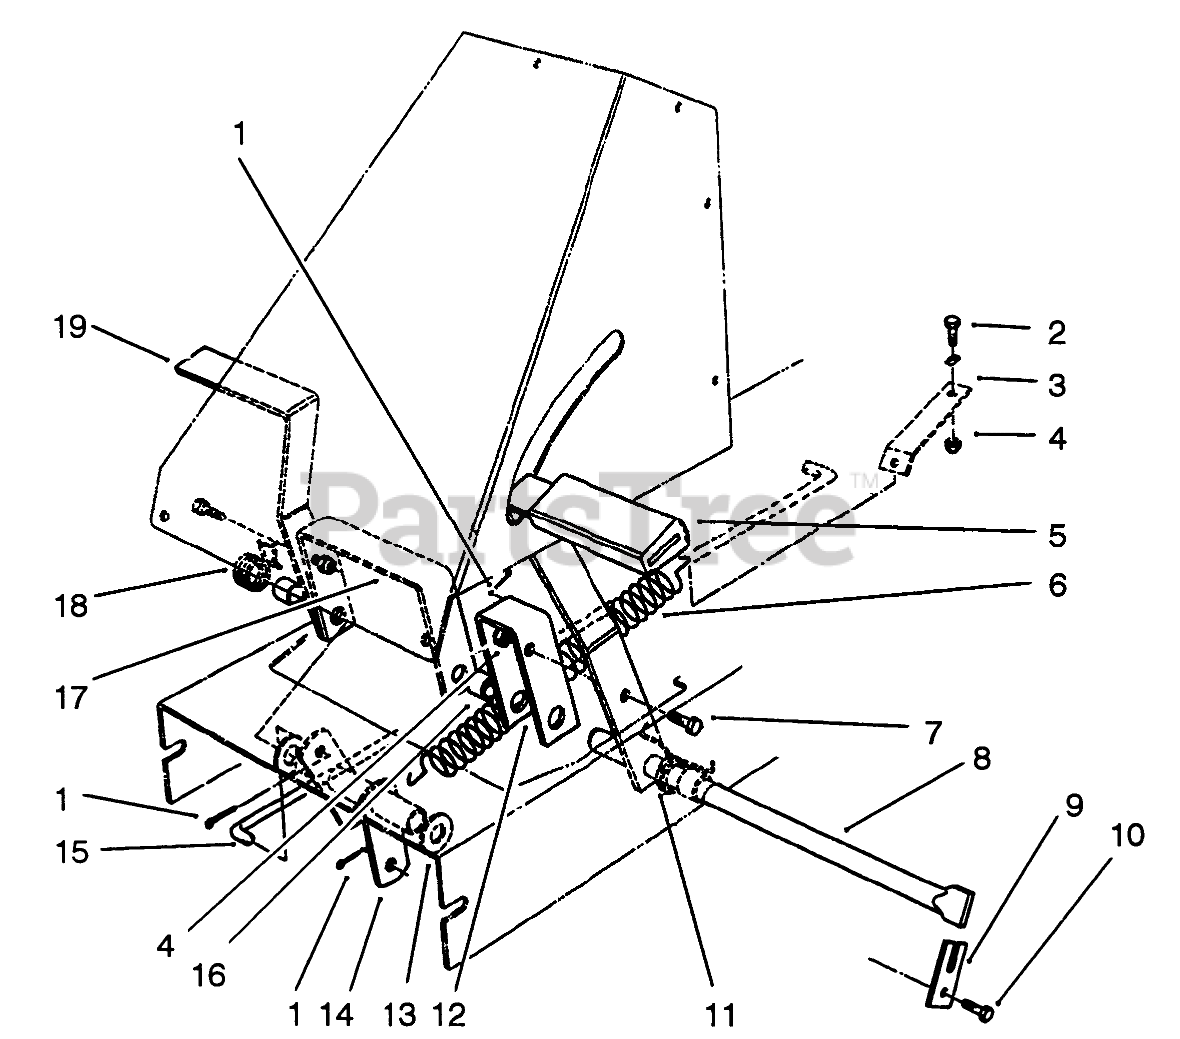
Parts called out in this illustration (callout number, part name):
1	PIN-COTTER
2	SCREW-HH
3	BRKT-SPRING RET
4	NUT-LOCK, NI
5	PAD-PEDAL
6	SPRING-EXTENSION
7	SCREW-HH
8	SHAFT-PEDAL PIVOT
9	RETAINER-SHAFT
10	SCREW-HH
11	SPRING-TORS CLUTCH
12	Bracket-Clutch Pedal
13	WASHER-FLAT
14	Pivot Tube
15	ROD-ENGAGE
16	SPACER-PEDAL
17	Bracket-Brake Pedal
18	SPRING-TORS BRAKE
19	Pedal
